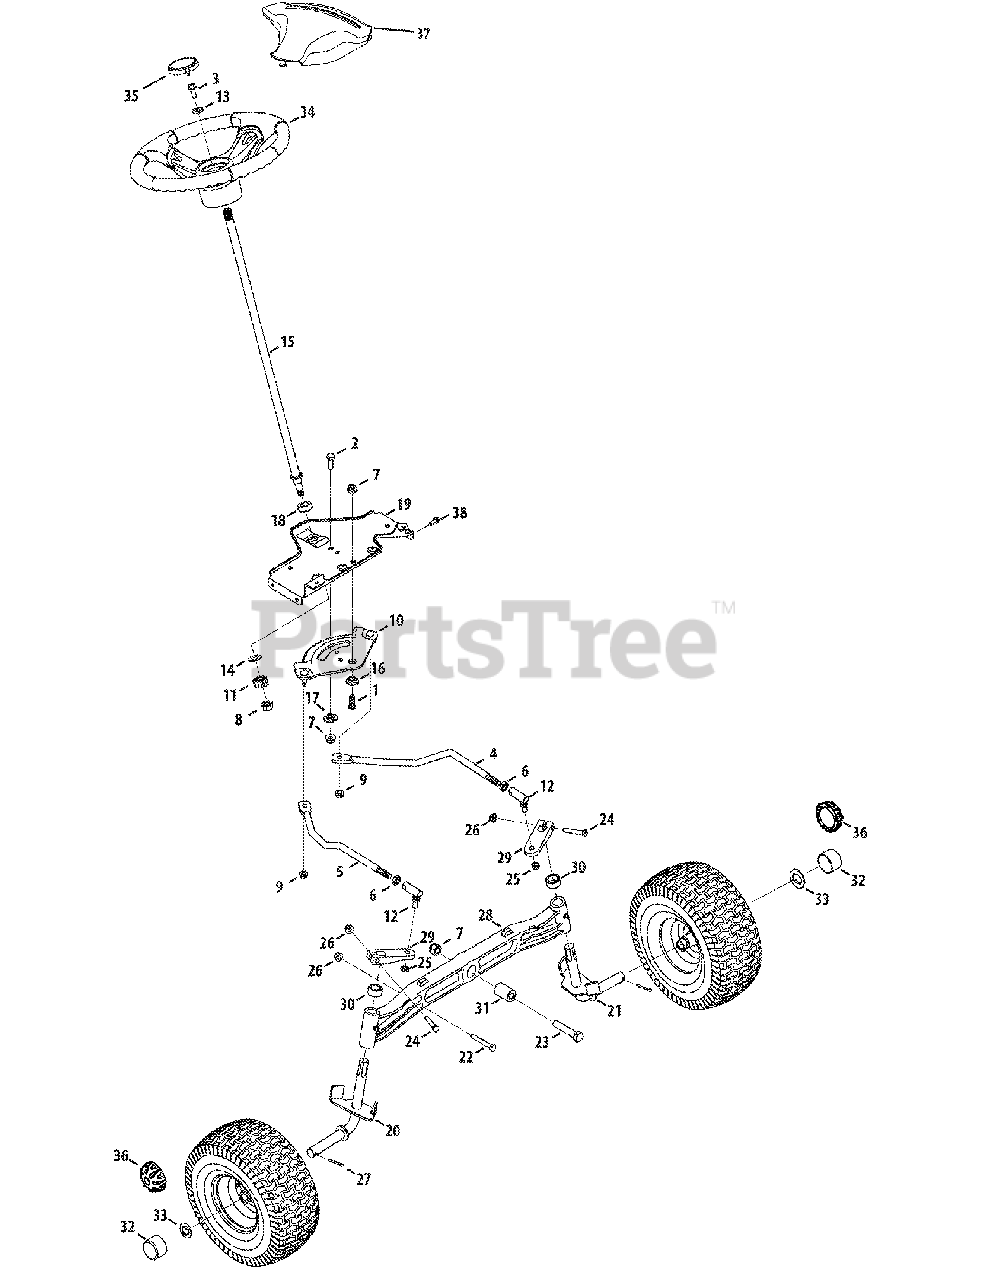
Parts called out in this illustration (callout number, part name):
1	Screw, 3/8-16 x 1.0
2	Hex Screw 3/16 x 1.00
3	Hex Screw 5/16-18 x 1.00 Special
4	Link, Drag LH
5	Link, Drag RH
6	Hex Jam Nut 7/16-20
7	Flange Lock-Nut 3/8-16 Gr. F Nylon
8	Flange Lock Nut, 7/16-20
9	Hex Flange L-Nut 5/16-18
10	Steering Gear, 11/90 Ratio
11	Steering Pinion Gear
12	Ball Joint, 7/16 - 20
13	Flat Washer .406 ID x .875 DE x .105
14	Flat Washer .510 x 1.120 x .060
15	Steering Shaft .625 OD x 24.25
16	Shoulder Spacer .385 x 1.25 x .3025
17	Shoulder Spacer .385 x 1.25 x .3025
18	Hex Flange Bearing 5/8
19	Steering Support Bracket
20	Axle Ass’y RH .750 Dia.
21	Axle Ass’y LH .750 Dia.
22	Hex Bolt 5/16-18 x 2.25
23	Hex Cap Screw, 3/8-16 x 2.5
24	Hex Screw 5/16-18 x 1.75" Lg.
25	Hex Cent L-Nut 3/8-24
26	Flange Locknut 5/16-18 Gr. F, Ny lon
27	Cotter Pin 5/32" Dia.
28	Pivot Bar (cast)
29	Steering Block
30	Spacer .710 ID x .125 OD x .56
31	Spacer .385 x 1.0 x 1.5075
32	Hub Cap
33	Flat Washer .350 x 1.559 x .062
34	Steering Wheel, Standard Grip
34	Steering Wheel, Softgrip
35	Steering Wheel Cap (sprig) logo
36	Hub Cap
37	Steering Wheel Cover (w/o sprigs)
38	S-Tapp Scr. 5/16-18 x .75
